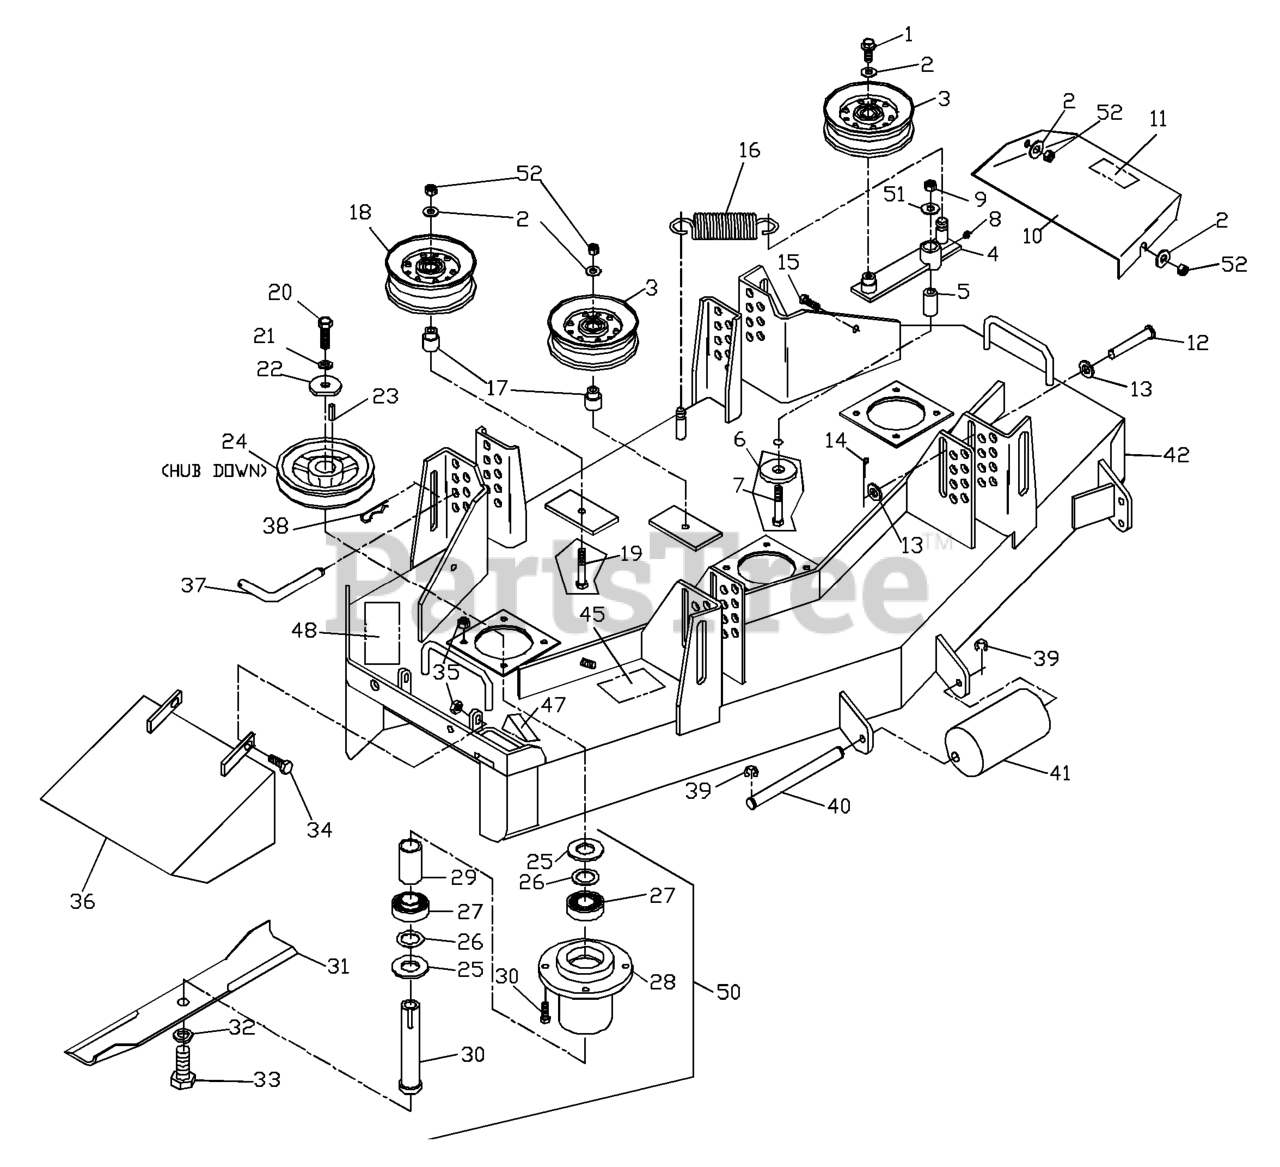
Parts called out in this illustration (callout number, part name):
1	4CS 3/8C X 1 SERRATED HEAD
2	WASHER 3/8 FLAT
3	IDLER PULLEY
5	PIVOT BUSHING
6	WASHER, SUPPORT
7	HCS 1/2C X 3 1/4
8	ZERK
9	NUT 1/2-13 HEX NYLOC ZD
10	BELT SHIELD, 42 RT
10	BELT SHIELD, 42, LEFT
11	DECAL, NO STEP
12	CLEVIS PIN
13	WASHER 1/2" FLAT
14	RP_COTTER PIN 1/8 X 3/4
15	HCS 3/8-16X1.GRD.5.ZD
17	IDLER BUSHING
18	IDLER PULLEY (TALL)
19	HCS 3/8C X 2 1/2
20	HCS 7/16F X 1 1/2
21	WASHER 7/16 LOCK
22	WASHER, CRANKSHAFT
23	KEY 1/4 SQ X 1 1/8
25	MACHINERY BUSHING 10 GA.
26	BUSHING.MACHINE.18.GAUGE
27	BEARING
30	SPINDLE SHAFT
31	BLADE OEM, 14-7/8
32	LOCKWASHER 5/8
33	HCS 5/8F X 1 1/4
34	HCS 5/16C X 1
35	NUT 5/16C CENTERLOCK
36	DEFLECTOR CHUTE
37	BENT ARM PIN
38	PIN .148 X 2-3/4 #10 ZD
39	E-RING 1/2 (2 2)
42	DECK W/DECALS 42"
47	DECAL, CPSC
48	DECAL, DANGER
50	HOUSING, COMPLETE
51	WASHER 1/2 FLAT
52	NUT 3/8C CENTERBLOCK
